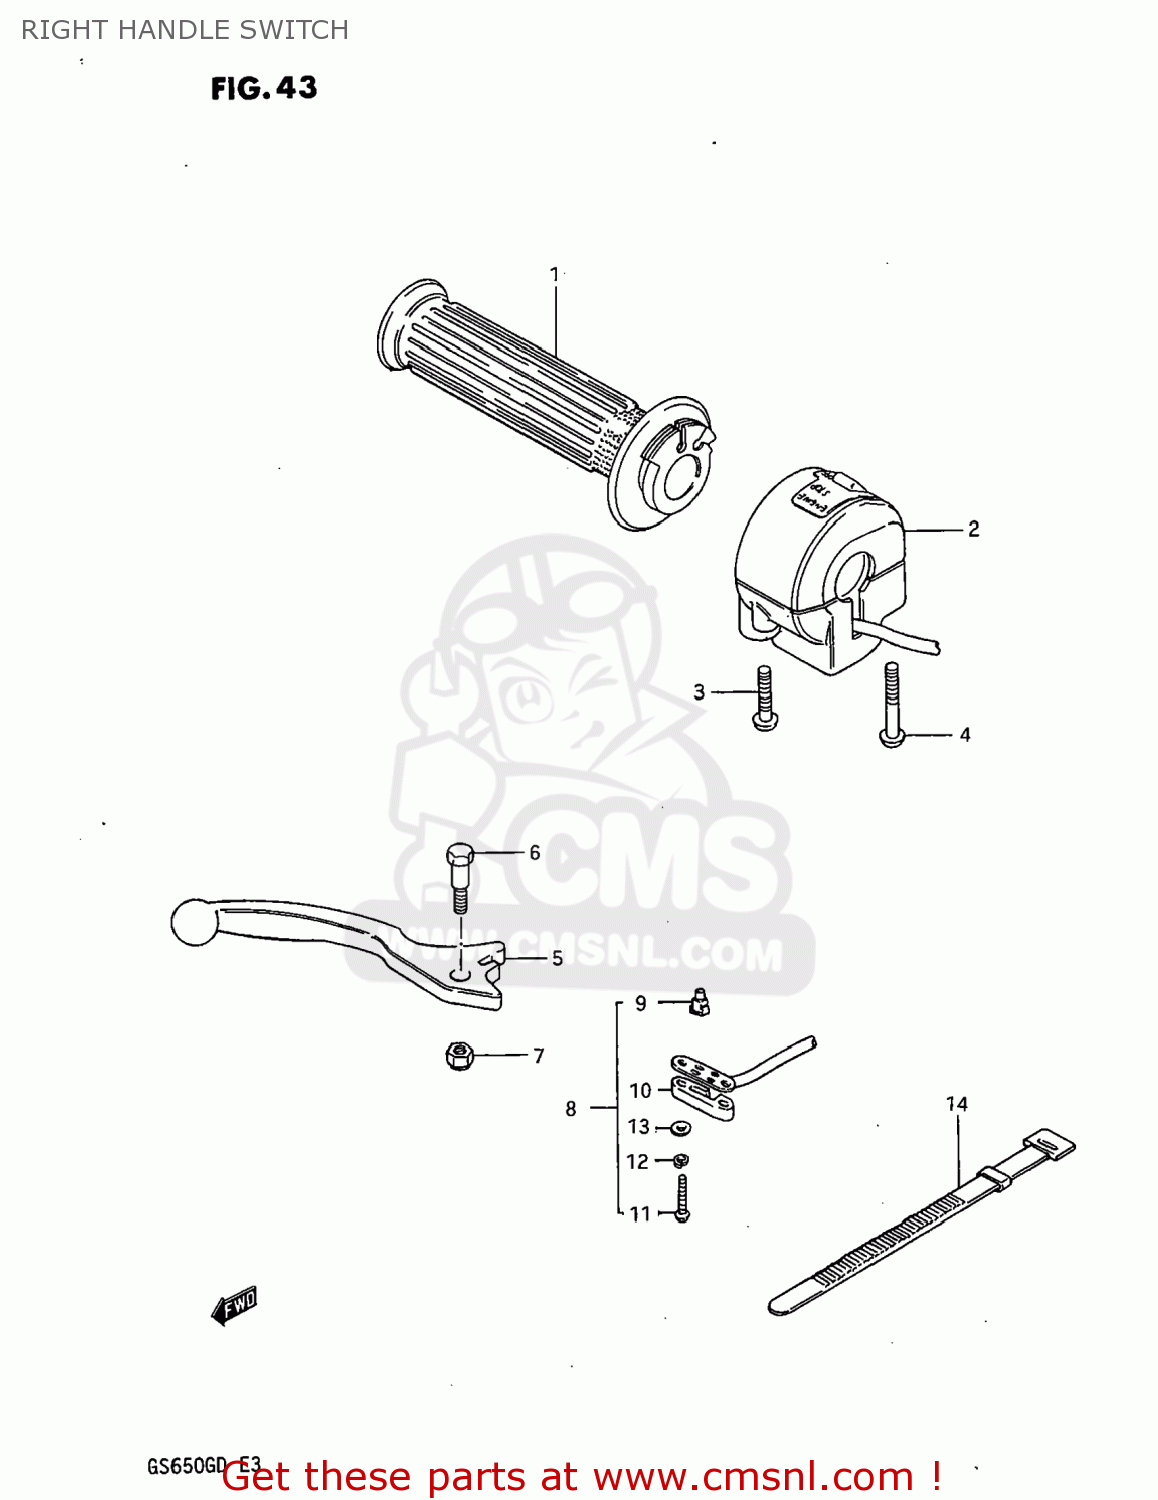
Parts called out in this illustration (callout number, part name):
1	GRIP,THROTTLE
2	SWITCH ASSEMBLY,HANDLE,RIGHT
3	SCREW
4	SCREW
5	LEVER,BRAKE
6	BOLT
7	NUT 6MM
8	SWITCH ASSEMBLY
9	CONTACT,SWITCH
10	COVER,FR BK TERMINAL BASE
11	SCREW
12	LOCK WASHER
13	WASHER
14	CLAMP(L:120)
